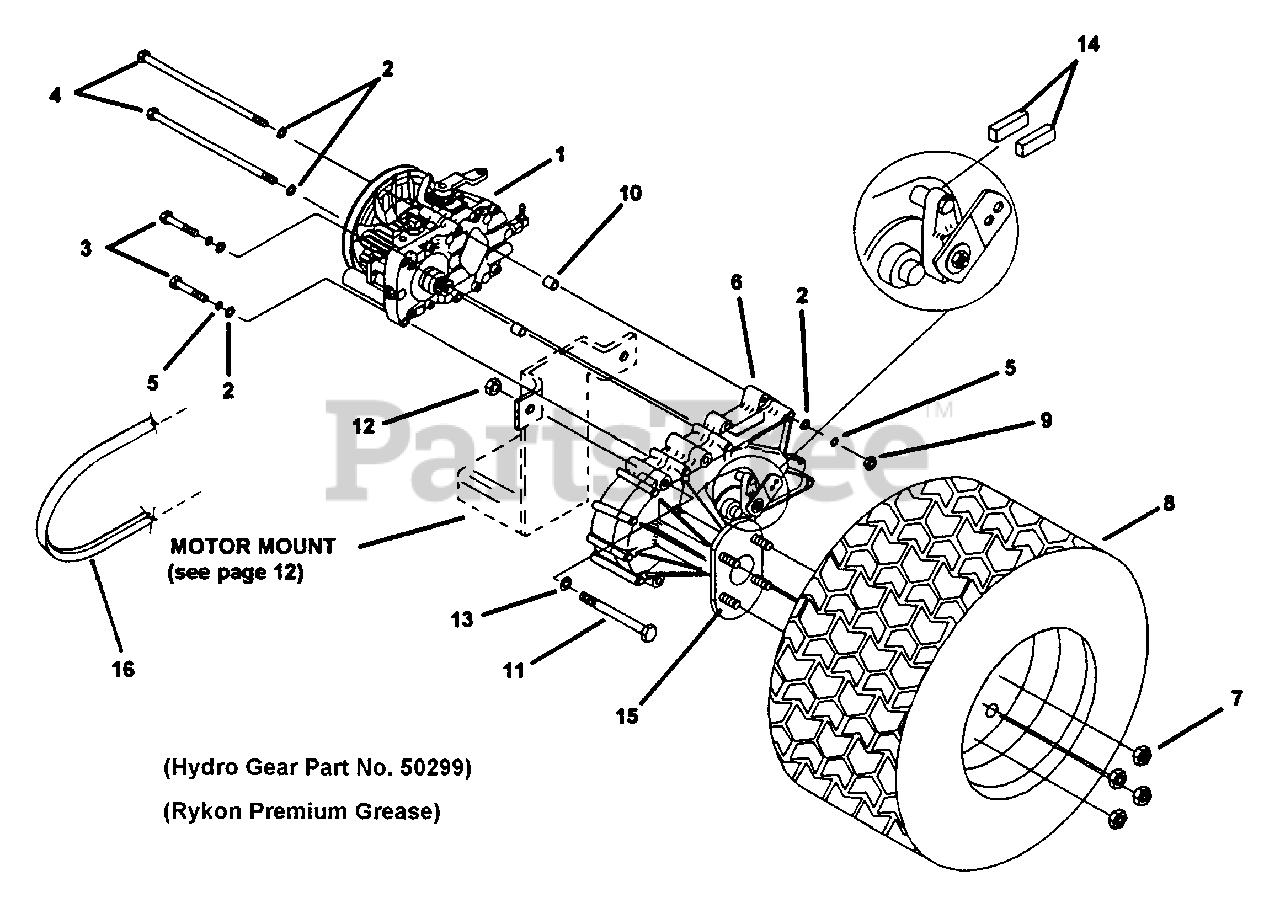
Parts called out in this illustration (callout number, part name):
1	HYDROSTAT TRANSMISSION ASSEMBLY L.H.
2	WASHER, FLAT STD. 5/16"
3	BOLT, 5/16-18 X 1-3/4" GR. 5
4	BOLT, 5/16-18 X 7-1/2" GR. 5
5	LOCKWASHER, 5/16" SPLIT SPRING
6	GEAR BOX, L.H.
7	NUT, LUG 60 DEGREE, 1/2-20
8	TIRE, 20-10.00-10, 4 PLY W/RIM
9	NUT, 5/16-18 PLAIN
10	BUSHING
11	BOLT, 3/8-16 X 4" GR.5
12	NUT, 3/8-16 NYLOC
13	WASHER, FLAT STD. 3/8"
14	BRAKE PUCK, REPLACEMENT
15	LUG BOLT
16	BELT, A-70 KEVLAR, MAIN DRIVE BELT
